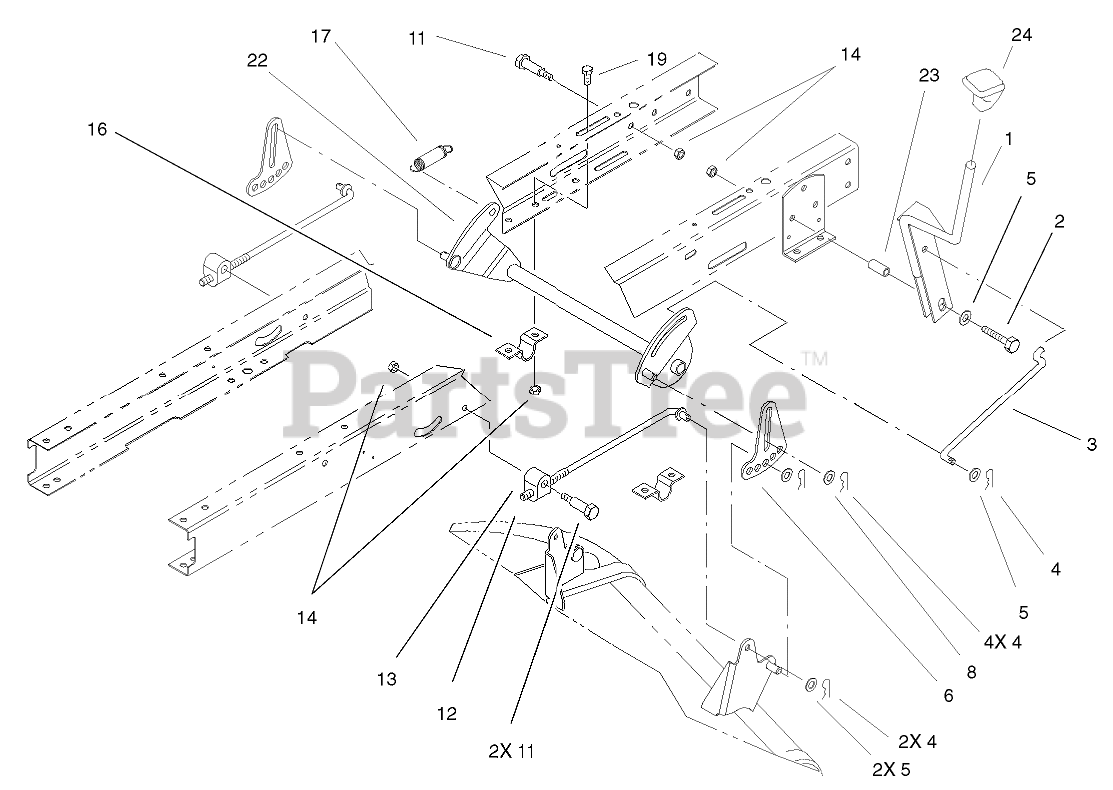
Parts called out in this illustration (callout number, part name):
1	HOC LEVER ASM
2	SCREW-HH
3	LINK-HOC
4	PIN-COTTER
5	WASHER-FLAT
6	LINK-ADJUSTING, HOC
8	WASHER-HARDENED
11	SCREW-SHOULDER, HH
12	ROD-HANGER, REAR
13	TRUNNION-HOC
14	NUT-LOCK, NI
16	CLAMP-PIVOT, HOC
17	SPRING-EXTENSION
19	SCREW-HH
22	PIVOT ASM
23	SPACER
24	KNOB-SHIFT
